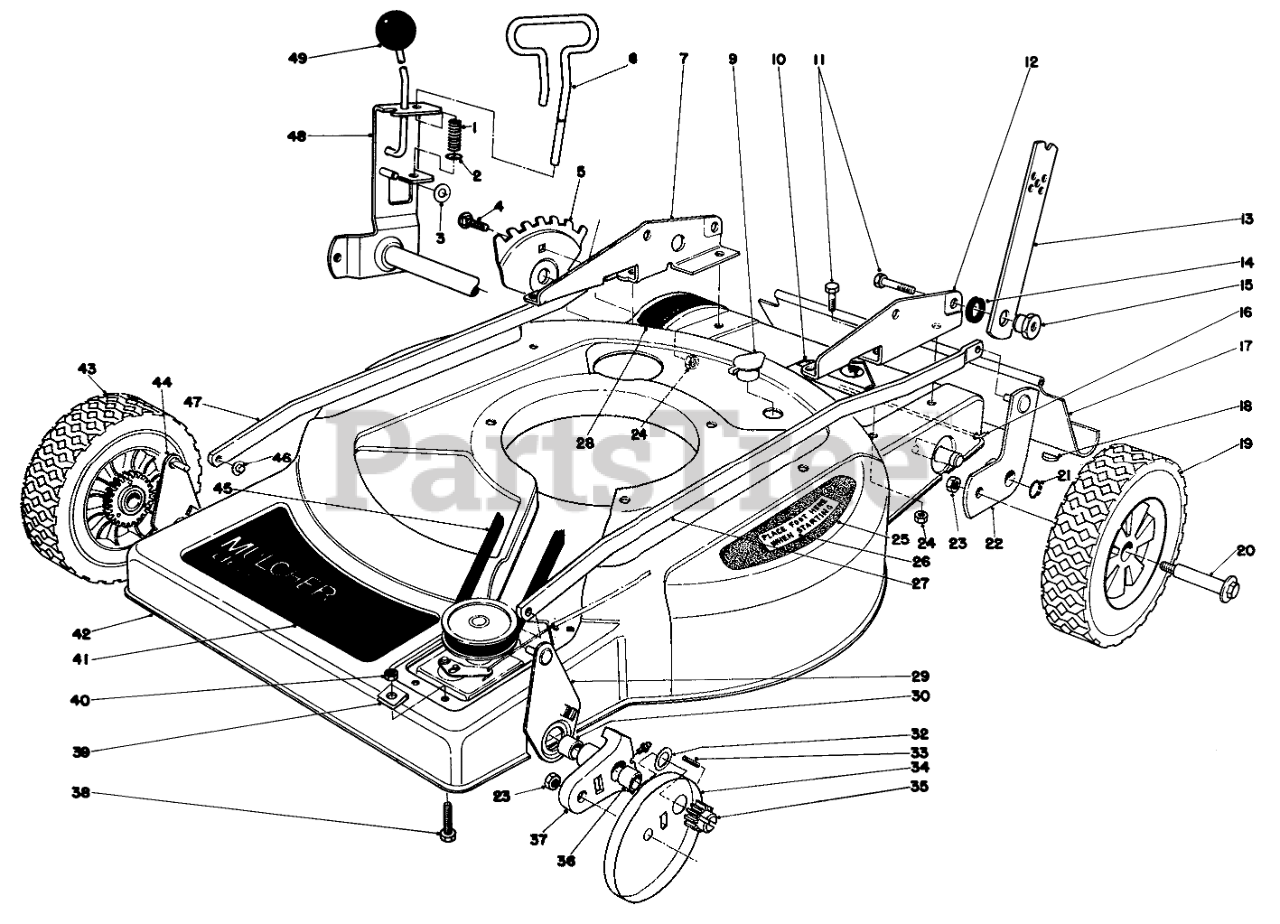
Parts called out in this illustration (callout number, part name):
1	SPRING-COMPRESSION
2	E-RING
3	WASHER-FLAT
4	Carriage Bolt
5	HOC ADJUSTMENT PLT
6	STOP ROD
7	Bracket Handle R.H.
9	WASHOUT PLUG
10	DECAL-DANGER
11	SCREW-HH
12	Bracket-Handle R.H.
13	HANDLE LATCH
14	SPACER
15	HANDLE PIVOT NUT
16	SHIELD ROD
17	SHIELD - TRAILING
18	KEY-WOODRUFF
19	WHEEL TIRE ASM 8 IN
20	BOLT-WHEEL
21	RING-RETAINING
22	Pivot Arm
23	Nut
24	NUT-LOCK, CONE
25	PAD STEP
26	Decal Step Pad
27	Spanner Link L.H.
28	Decal Height of Cut
29	PIVOT ARM LINK WA
30	BUSHING
32	WASHER-THRUST
33	Pin
34	WHEEL COVER
35	Pinion
36	BUSHING
37	Pivot Arm (Incl. Ref. #30 & 36)
38	SCREW
39	SPEED NUT
40	NUT-JAM
41	Decal-Deck
42	Housing
43	Wheel & Tire Assembly
44	PIVOT ARM LINK WA
45	V BELT
46	NUT-SPEED
47	Spanner Link R.H.
48	Pivot Arm Bracket
